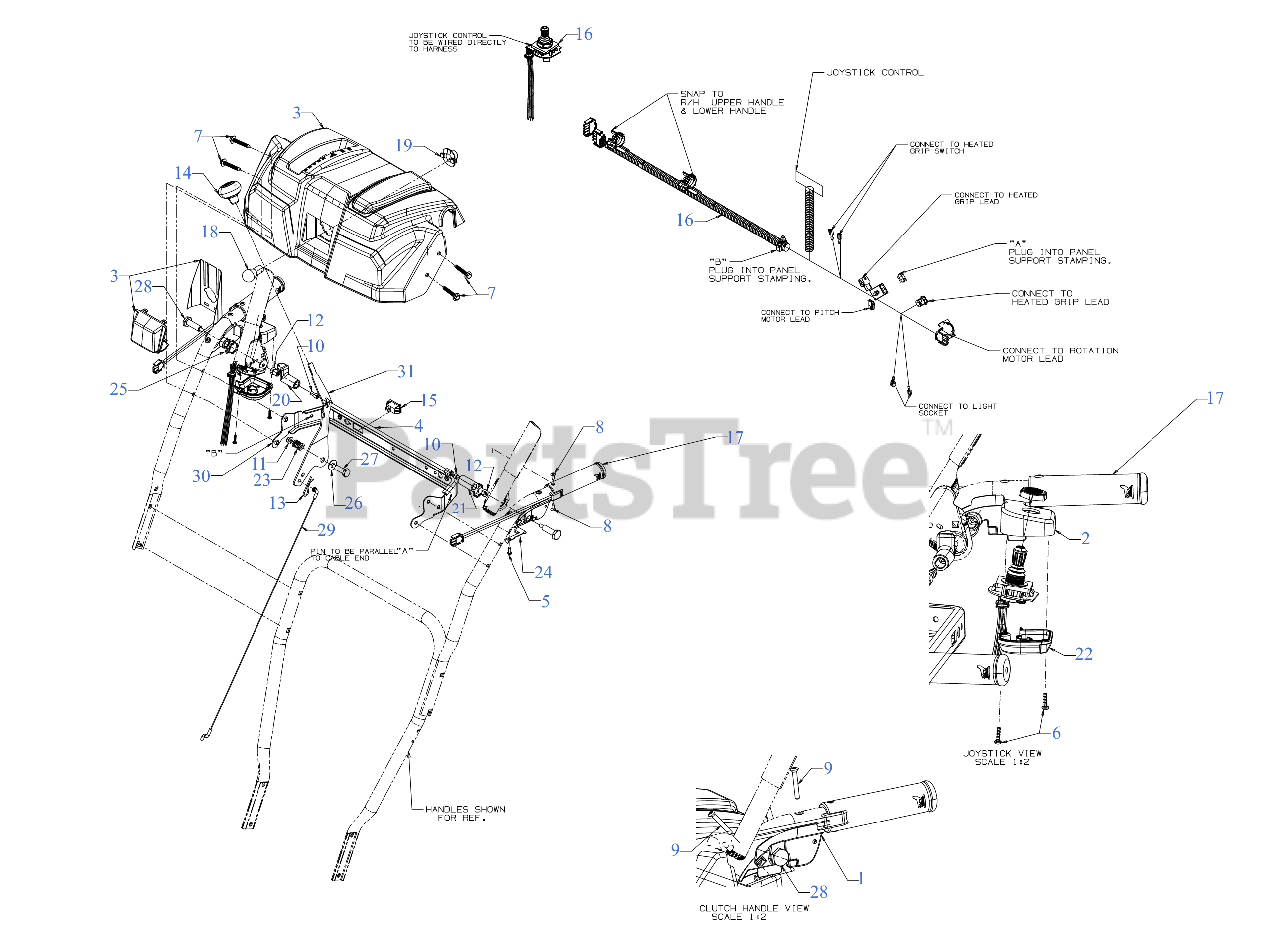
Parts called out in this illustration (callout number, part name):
1	CLUTCH LOCK HANDLE ASSEMBLY (LH)
2	CLUTCH HANDLE ASSEMBLY (RH)
3	HANDLE PANEL ASSEMBLY
5	SCREW #8-16 x .50
6	SCREW .159 x .610
7	SCREW 1/4-20 x 1.625
8	SCREW #10-16 x .625
9	SCREW #10-24 x 1.375
10	SCREW 1/4-20 x .50
11	FLANGE LOCK NUT
12	HEX NUT W/PATCH
13	INTERNAL COTTER PIN
14	SHIFT KNOB
15	HEATED GRIP SWITCH
16	4-WAY ELEC/HEAT GRIP HARNESS
17	HARNESS-SNOW HEATED GRIP RED
18	LAMP-12 VOLT
19	HEADLIGHT SOCKET
21	CLUTCH LOCK CAM
22	JOYSTICK HOUSING COVER
23	COMPRESSION SPRING
24	CLUTCH SPRING
25	TORSION SPRING
26	FLAT WASHER .40X.88X.060
27	SHOULDER SCREW
28	SHOULDER SCREW .437 x 1.345 1/4-20
29	SPEED SELECTOR CABLE (PLASTIC)
30	HANDLE SUPPORT BRACKET (POWDER BLACK)
